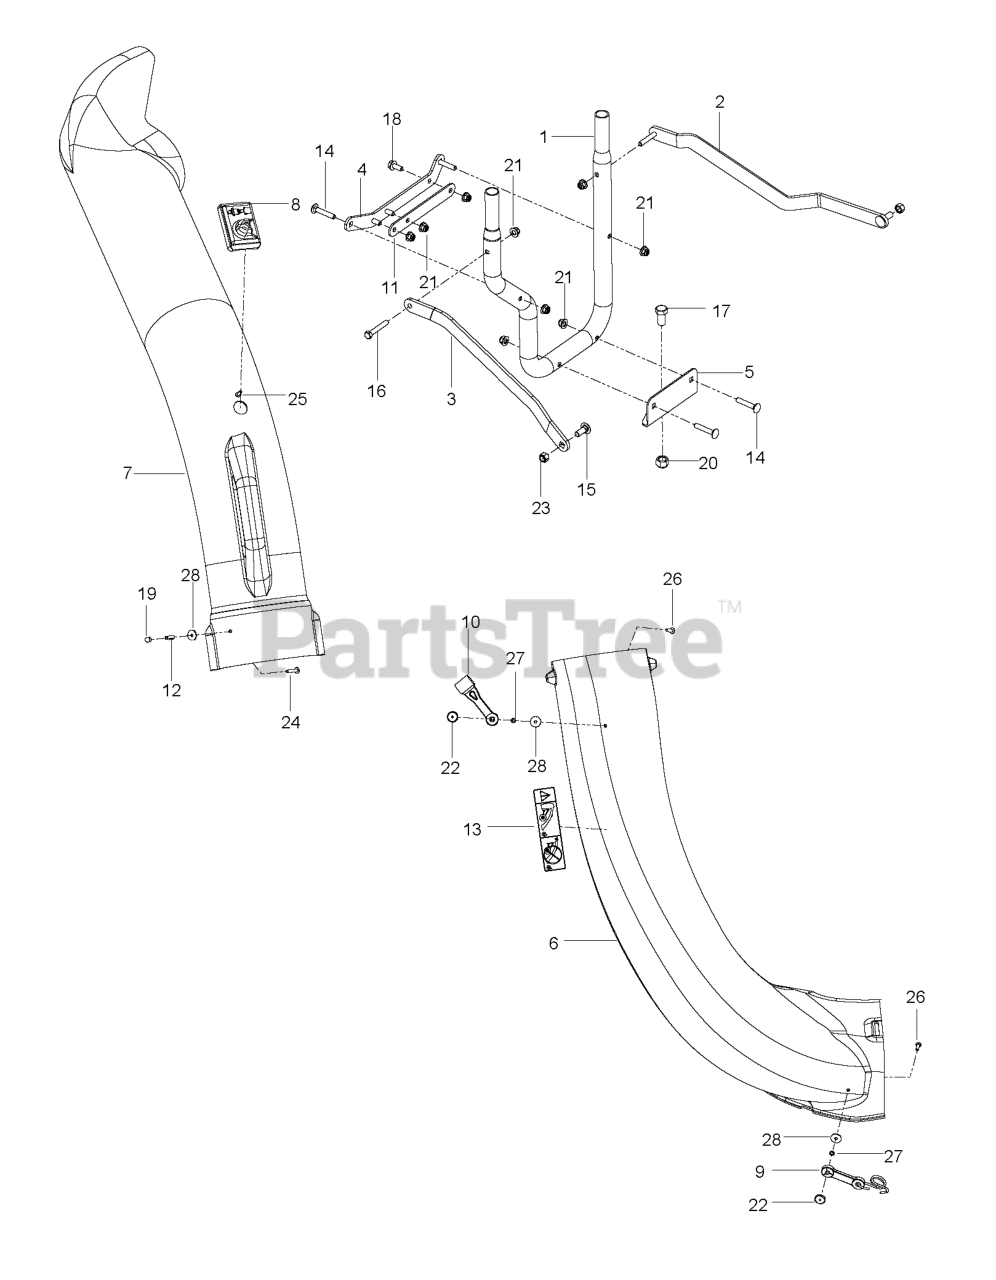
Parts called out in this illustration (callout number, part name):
1	MOUNT.TUBE.COLLECTIONS
2	STRAP.LH.BLACK
3	STRAP.RT.BLACK
4	BRKT, SUPPORT, BLK
5	MOUNT, HITCH, LOWER
6	CHUTE, LOWER 54
7	CHUTE.COLLECTION.UPPER
8	DUMP BAG INDICATOR
9	LATCH ASSY TBR
10	HOOD LATCH
11	SPACER, PLATE, BLK
12	BSHG .202X.75 LG SPLIT ZD SPEC
13	DECAL, CHUTE
14	RHSNB 5/16-18X1 3/4
15	RHSNB 3/8C X 1
16	HCS 5/16-18X2
17	HHCS 1/2-13 X 1
18	HHFS 5/16-18 X 3/4
19	NUT 10-24 ACORN ZD
20	NUT 1/2-13 HEX NYLOC ZD
21	5/16-18 NYLOC FLANGE NUT
22	NUT 10-24 WELD PLATED
23	NUT 3/8-16 NYLOC
24	SCREW #10-24 X 1-1/8 ZD SPEC
25	SCREW
26	SCREW #10-24 X 5/8
27	WASHER - 3/16 LOCK ZD
